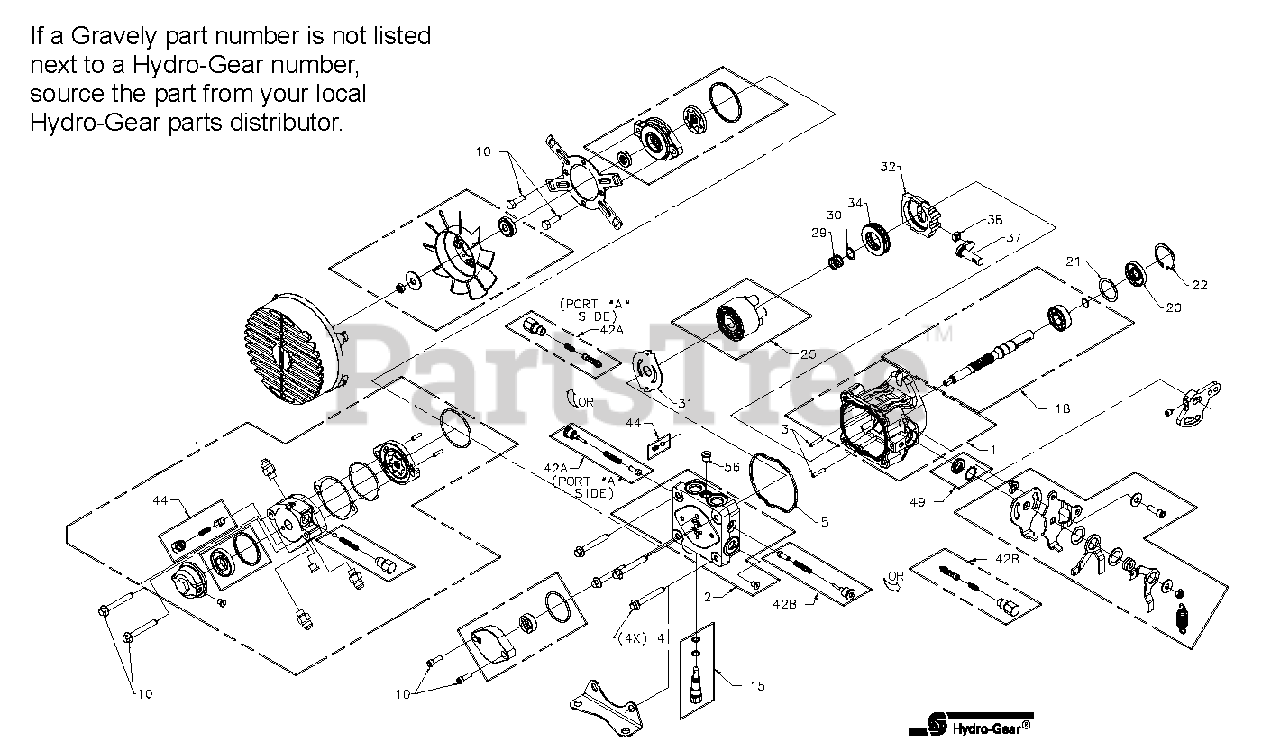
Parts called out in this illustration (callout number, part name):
1	Kit, Housing
2	Kit, End Cap W/PPT & STD
3	Pin, .219 x 1
4	Hex, Flange Bolt M8-1.25 x 60mm
5	Kit, Chg Pump
10	Screw, Cap M6 x 1 x 25
15	Kit, Bypass Valve
18	Kit, Pump Shaft 15mm Key
20	Seal, Lip 17 x 40 x 7
21	Washer 1.23 x 1.56 x .04
22	RING- RET 1.56 INT
25	Kit, 10 CC Block
29	Spring, Block
30	Washer, Thrust .59 x .78 x .04
31	Plate, Valve
32	Swashplate 10cc
34	Bearing, Thrust Ball 30 x 52 x 13
37	Arm, Trunnion 10 Cc
38	Guide, Slot
42	Kit, Shock Valve 200 Bar
44	Kit, Chg Relief
49	Kit, BDP-10l Seal
56	Plug 7/16-20 (Metal)
NS	Kit, Overhaul Seal
